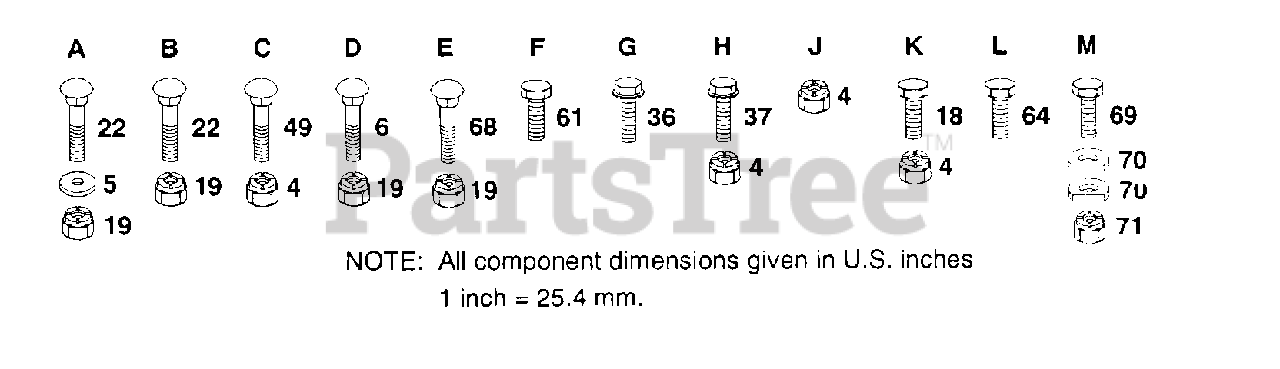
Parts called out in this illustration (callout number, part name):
5	WASHER M
6	BOLT
22	BOLT
36	SCREW
37	SCREW
49	BOLT
61	BOLT
64	BOLT.3/8-14X1.25
69	BOLT LT
70	WASHER T
